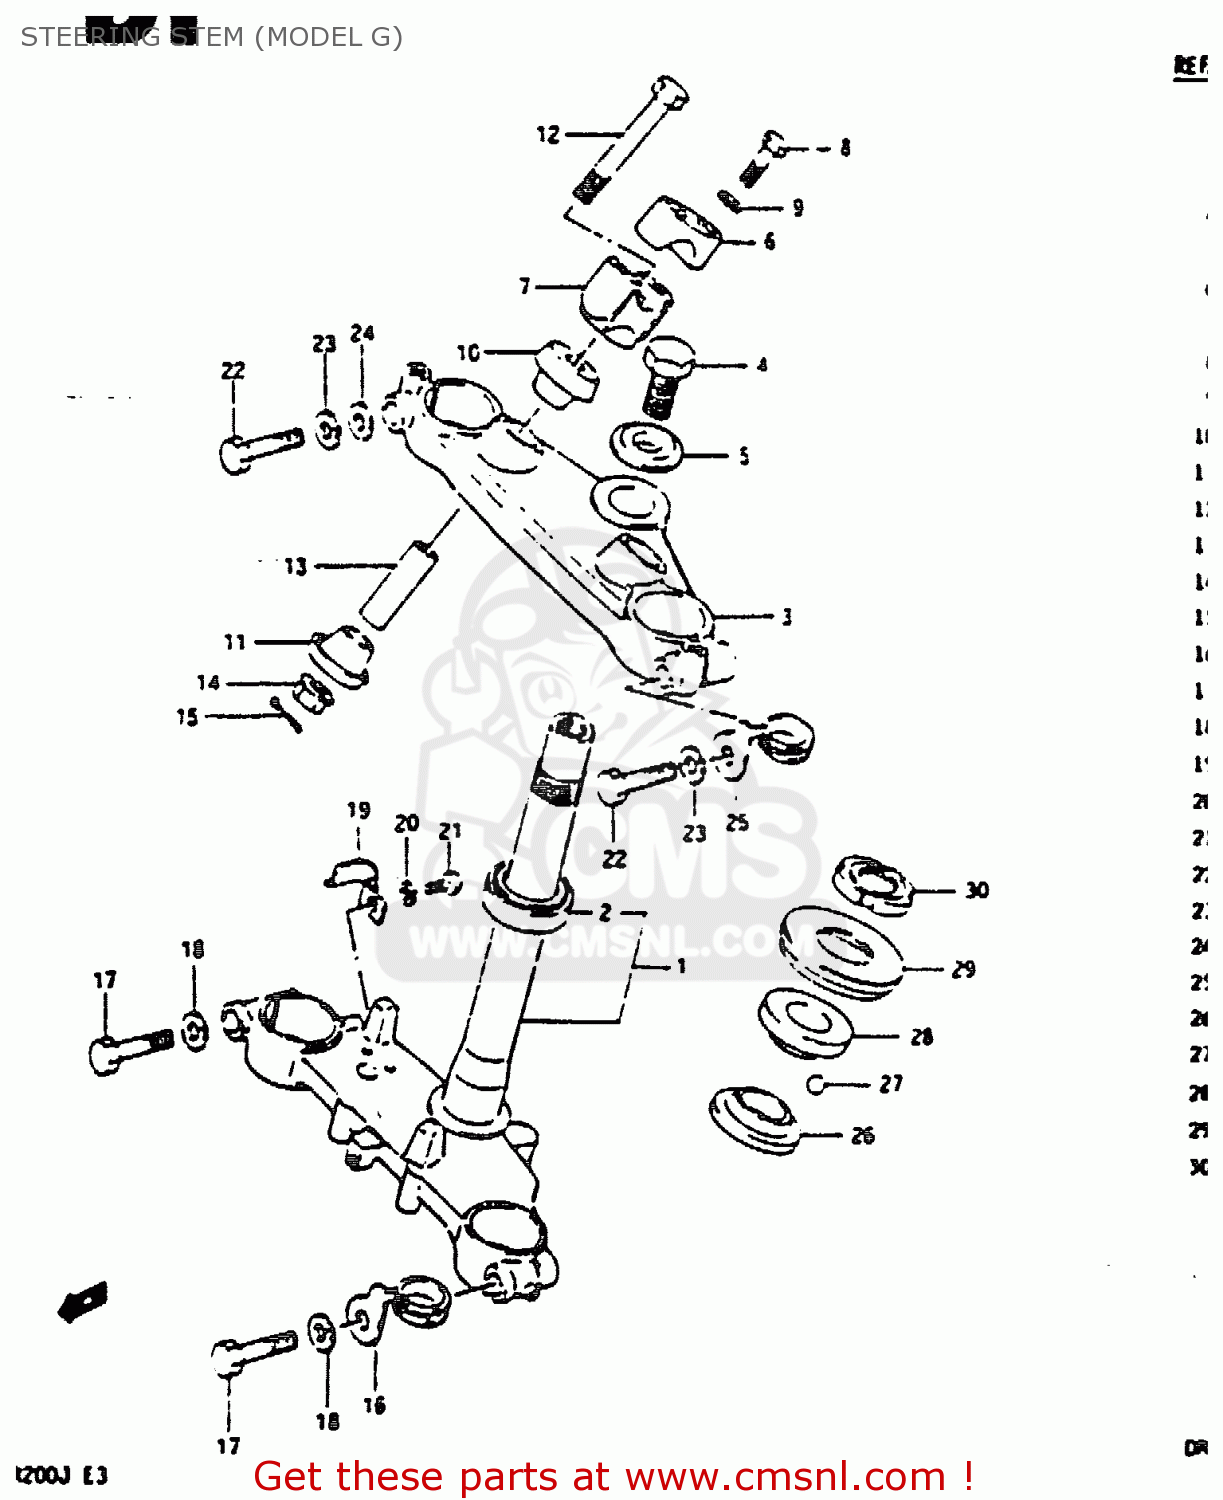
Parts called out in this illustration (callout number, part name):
1	STEM,STEERING
2	BEARING
3	HEAD,STEERING STEM
4	BOLT,STEERING STEM
5	WASHER
6	HOLDER,HANDLEBAR
7	HOLDER,HANDLEBAR,LOWER
8	BOLT
9	LOCK WASHER
10	CUSHION
11	RUBBER,LOWER
12	BOLT
13	SPACER
14	NUT
15	COTTER PIN
16	CLIP,UPPER
17	BOLT,FORK INNER TUBE FITTING
18	LOCK WASHER
19	CLIP
20	WASHER,LOCK
21	SCREW
22	BOLT,FORK INNER TUBE FITTING
23	LOCK WASHER
24	WASHER
25	CLIP,UPPER
26	RACE,STEERING,INNER,UPPER
27	BALL
28	RACE,STEERING,OUTER,UPPER
29	SEAL,STEERING UPR DUST
30	NUT,STEERING STEM
